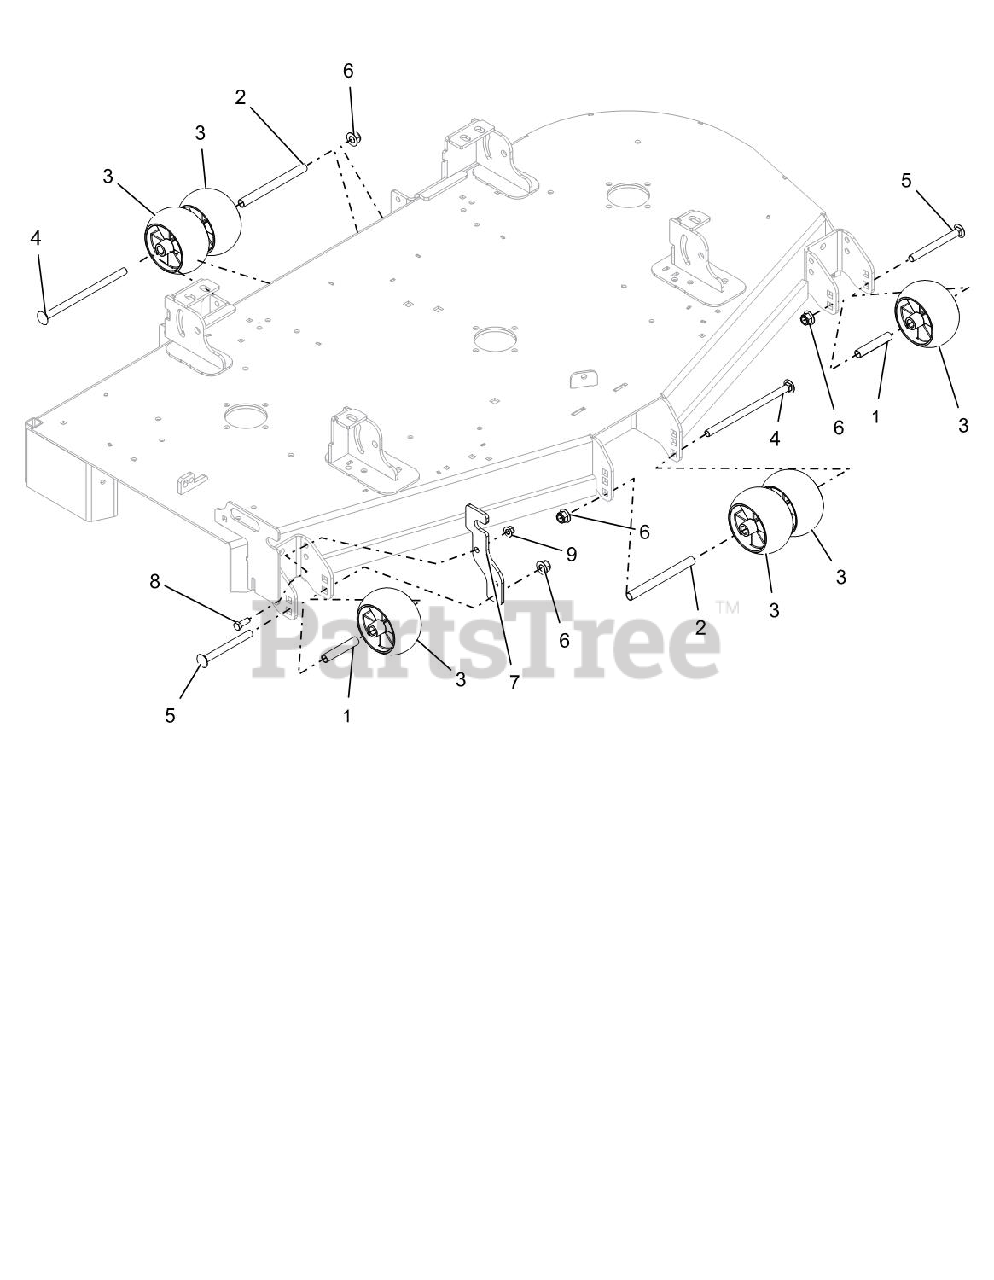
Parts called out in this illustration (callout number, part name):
1	SPACER, .510X.625X3.35
2	SPACER, .510X.625X6.50
3	ANTI-SCALP WHEEL - 5X3 CTR
4	BLT-RDHDSQNK .50-13X8.50 G5YZ
5	BLT-RDHDSQNK .50-13X5.00 GR5YZ
6	NUT-LK-NYL-FLG .50-13 YWZC
7	CHUTE STORAGE BRACKET - RED
8	BLT-HEX .38-16X1.00 GR5 YWZC
9	NUT-LK-NYL-FLG .38-16 YWZC
